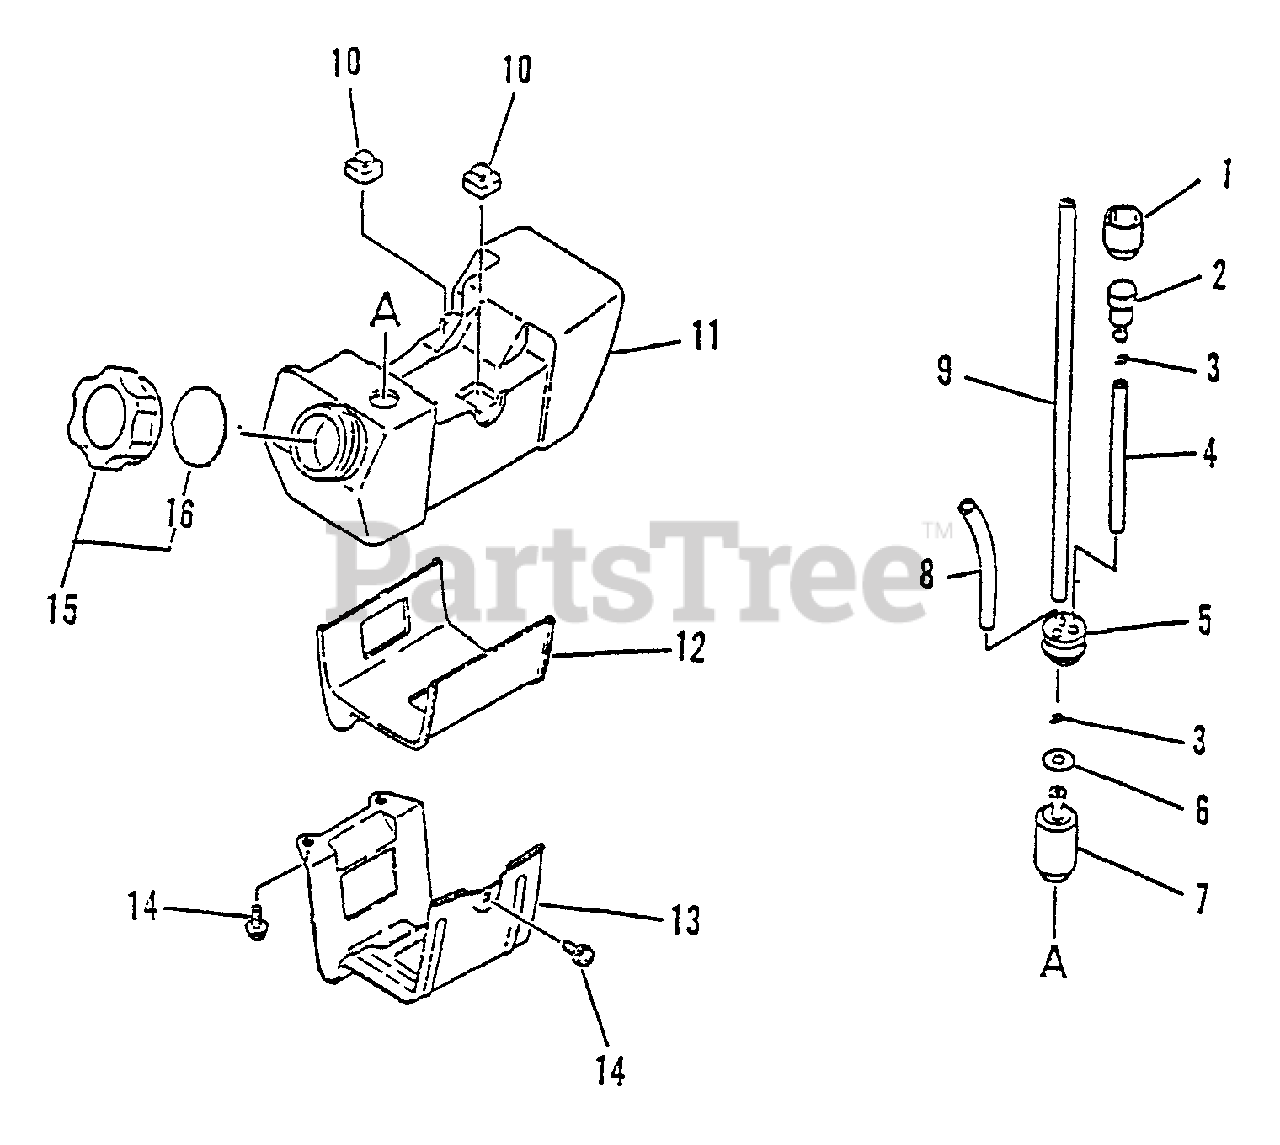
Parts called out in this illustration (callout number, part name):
1	COVER, VENT
2	VENT, FUEL TANK
3	CLIP - 5.5
4	PIPE - 3X6X70 -- BLACK
5	GROMMET
6	WASHER - 5
7	FILTER, FUEL
8	PIPE - 3X6X90 -- CLEAR
9	PIPE - 3X5X180 -- BLACK
10	CUSHION
11	TANK, FUEL
12	CUSHION
13	GUARD, FUEL TANK
14	SCREW - 5X10
15	CAP ASSY
16	GASKET, CAP
